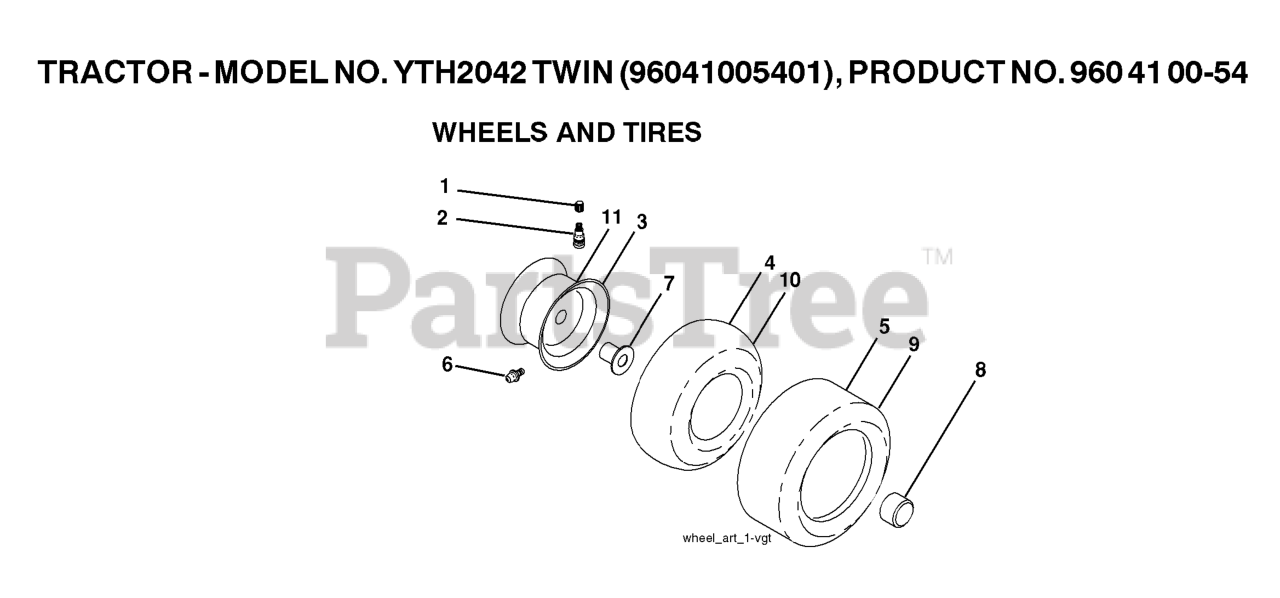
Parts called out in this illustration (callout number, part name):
2	VALVE STEM LT
3	RIM ASM 6" FRONT SILVER
4	TUBE.5.3/4.5/6
5	TIRE HEAVY DUTY
6	FITTING LT
7	BEARING T
8	CAP, AXLE BLK
9	TIRE.TS.20X10-8
10	TUBE
11	RIM ASM 8" REAR SILVER
